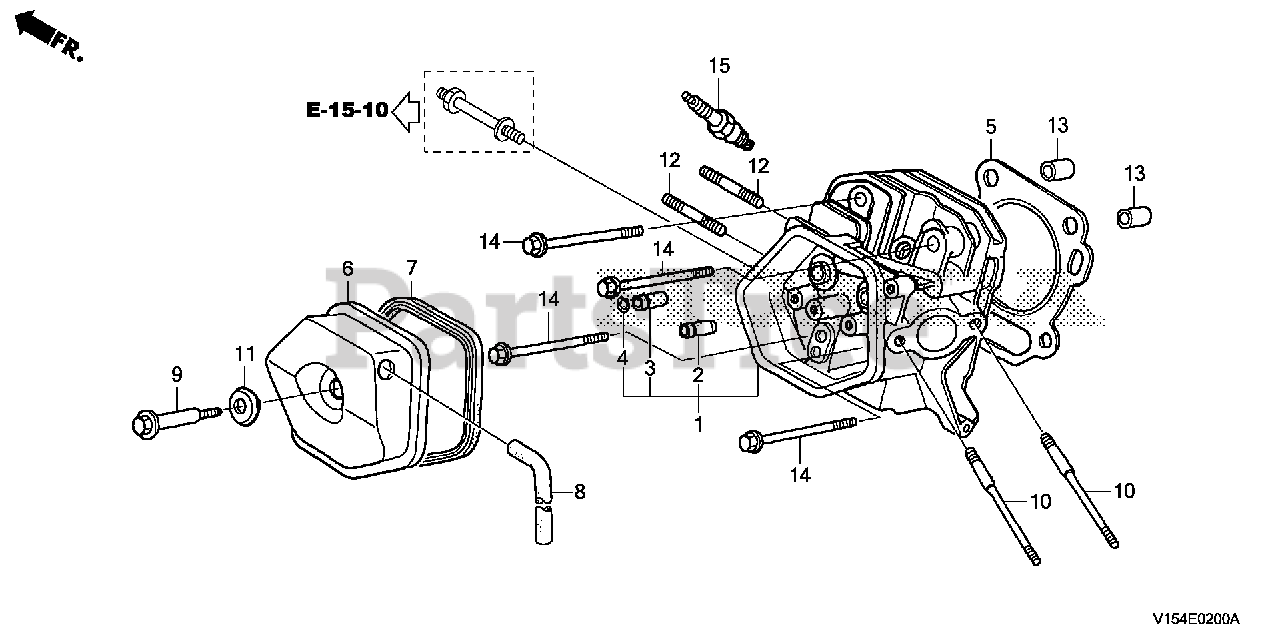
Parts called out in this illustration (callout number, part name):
1	CYLINDER HEAD
2	GUIDE, VALVE (OS)
3	GUIDE, EX. VALVE (OS)
4	CLIP, VALVE GUIDE
5	GASKET, CYLINDER HEAD (NIPPON LEAKLESS)
6	COVER, HEAD
7	GASKET, CYLINDER HEAD COVER
8	TUBE, BREATHER
9	BOLT, HEAD COVER
10	BOLT, STUD (8X134.5)
11	WASHER, HEAD COVER
12	BOLT 2, STUD (8X32)
13	PIN A, DOWEL (12X20)
14	BOLT, FLANGE (10X80)
15	SPARK PLUG (BPR5ES) (NGK)
